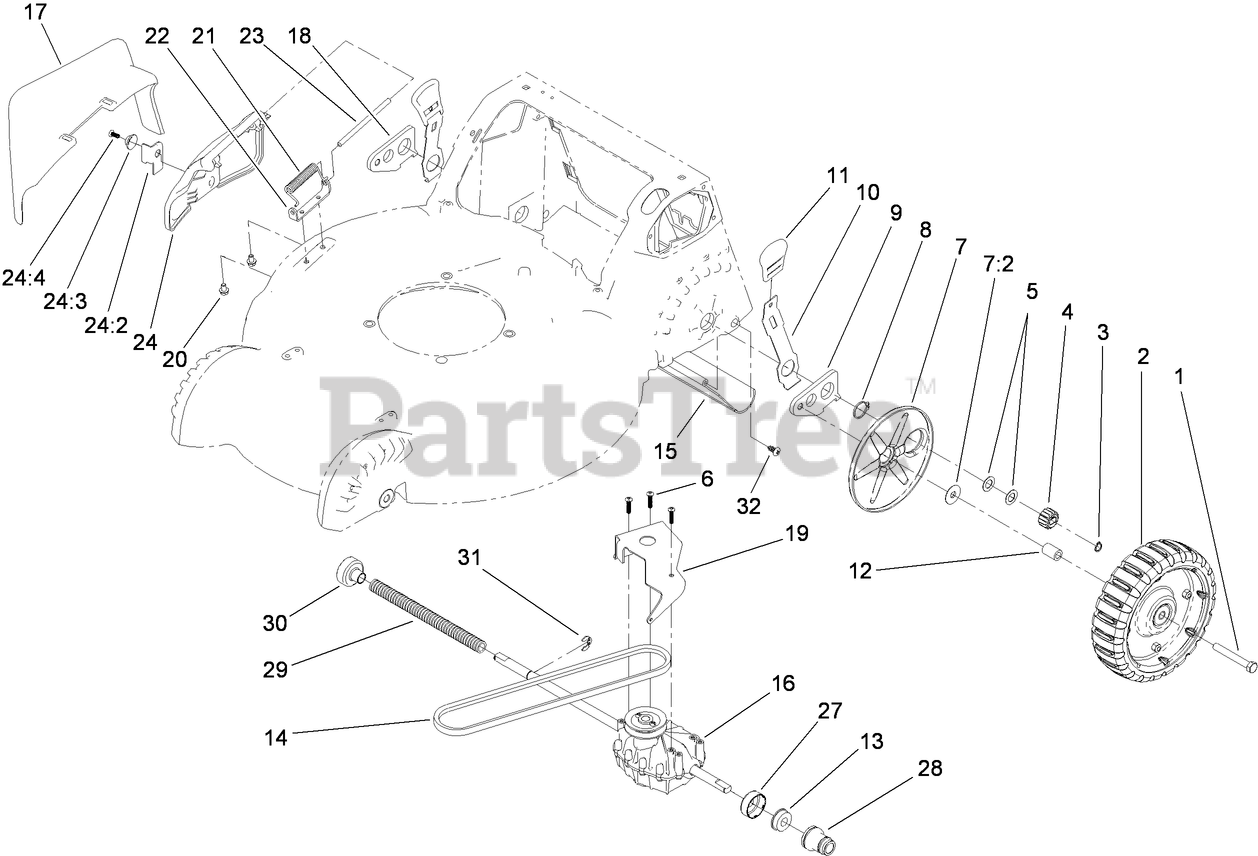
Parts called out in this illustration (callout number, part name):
1	SCREW-HH
2	8-INCH WHEEL ASM
3	RING-RETAINING
4	GEAR-PINION, 15T
5	WASHER-PLAIN
6	SCREW-PLASTITE
7	WHEEL COVER ASM
7:2	WASHER-STEPPED
8	RING-RETAINING
9	ARM-REAR PIVOT, LH
10	ARM-SPRING, REAR
11	KNOB-HOC
12	SPACER
13	BEARING-BALL
14	V-BELT
15	SHIELD-TRAILING
16	TRANSMISSION
17	CHUTE-DISCHARGE, SIDE
18	ARM-REAR PIVOT, RH
19	BRACKET-TRANSMISSION
20	SCREW-HWH
21	SPRING-TORSION
22	BRACKET-COVER
23	ROD-COVER
24	DISCHARGE DOOR ASM
24:2	LATCH-DOOR
24:3	CAP-DOOR
24:4	SCREW-PLASTITE
27	Cover-Bearing
28	RETAINER-BEARING
29	Cover-Shaft, Drive
30	CAP-BEARING
31	RING-CLIP, LOCKING
32	SCREW-PTH
